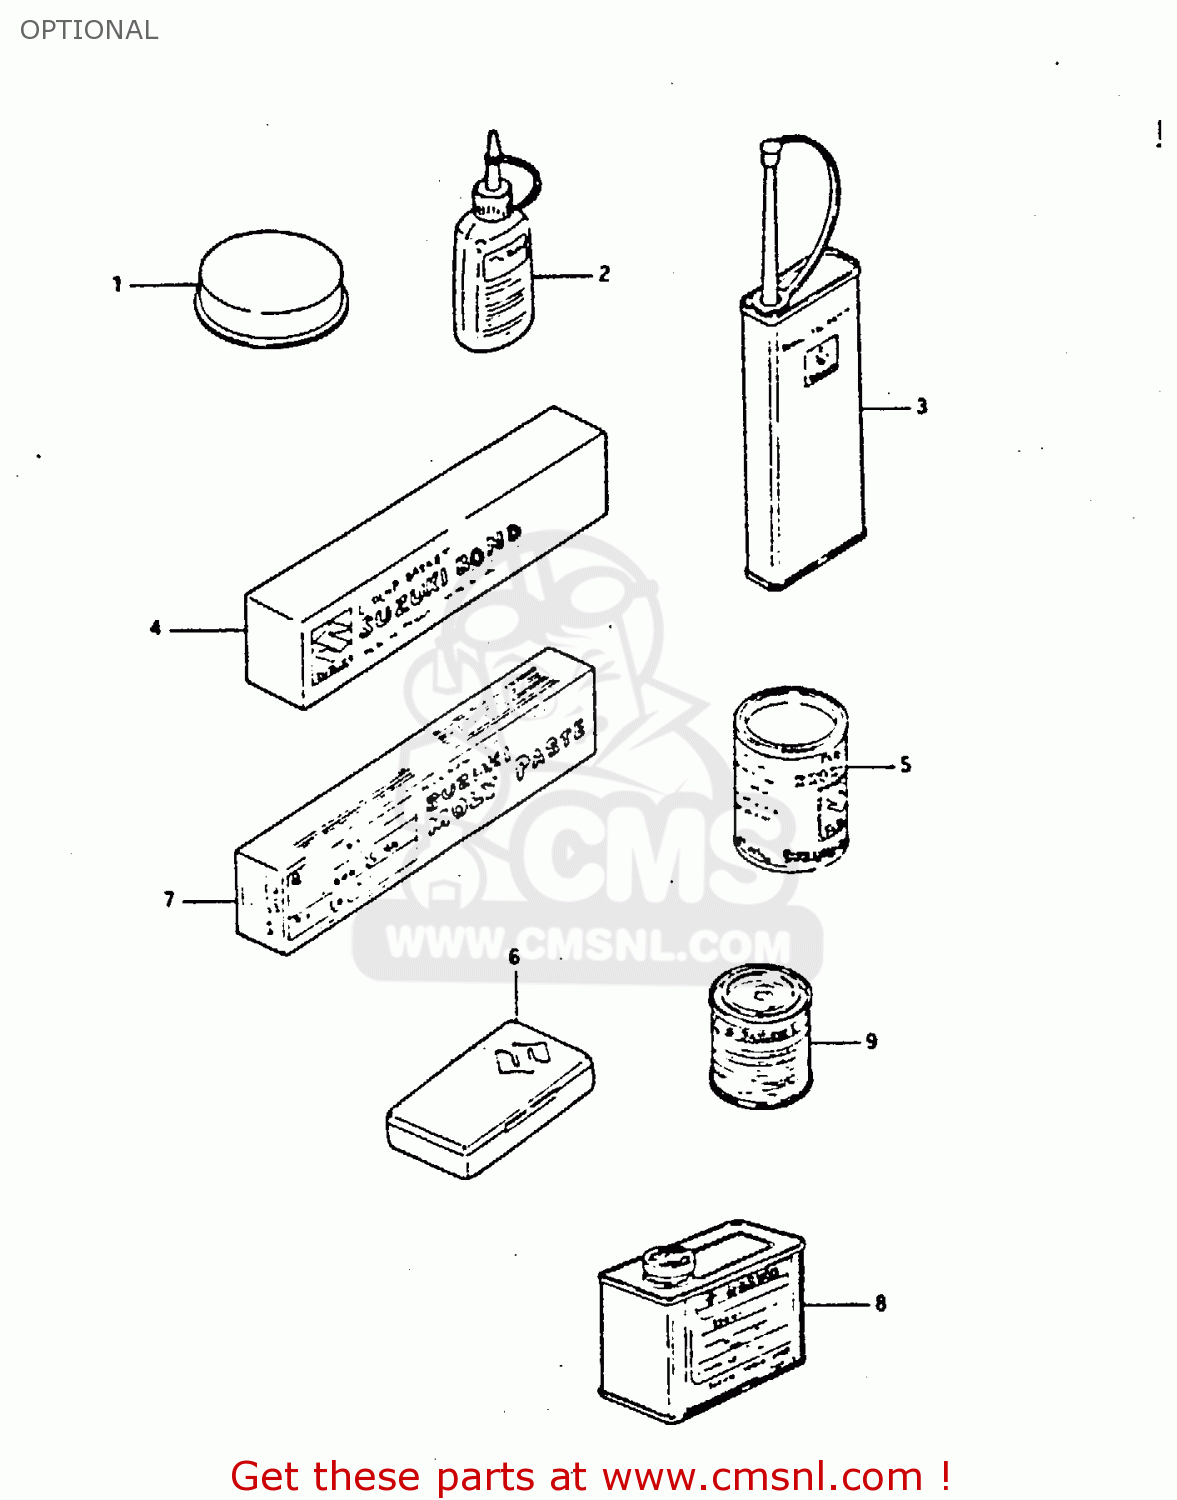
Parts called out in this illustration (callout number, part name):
1	GREASE,PBC FOR BRK PAD 20G
2	THREAD LOCK NO.1342
3	THREAD LOCK NO.1401 CLEAR 200G
4	LIQUID GSKT NO.1207B 100G BLK
5	GREASE(C)EP2 LITHIUM 150G
6	TUBE REPARING TOOL
7	SUZUKI MOLY PASTE
8	PAINT (BLACK)
9	PAINT,BLACK
